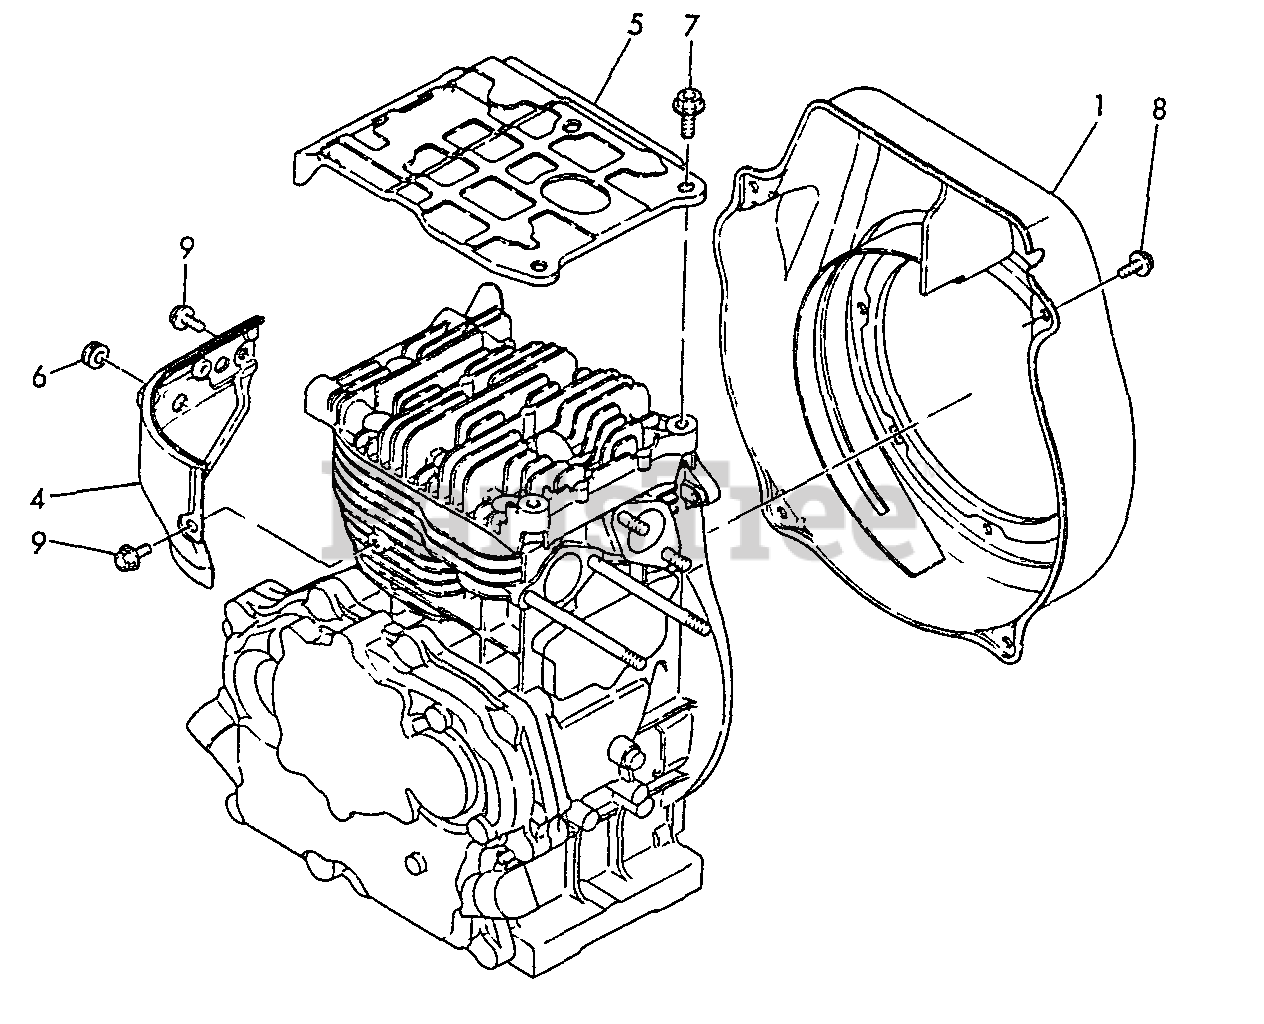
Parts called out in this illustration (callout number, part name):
1	COVER, FAN - INNER
4	SHIELD, CYLINDER
5	COVER, HEAD
6	GROMMET
7	BOLT - 8×20 -- PLATED
8	BOLT - 6×8 -- PLATED
9	BOLT - 6×8 -- PLATED
